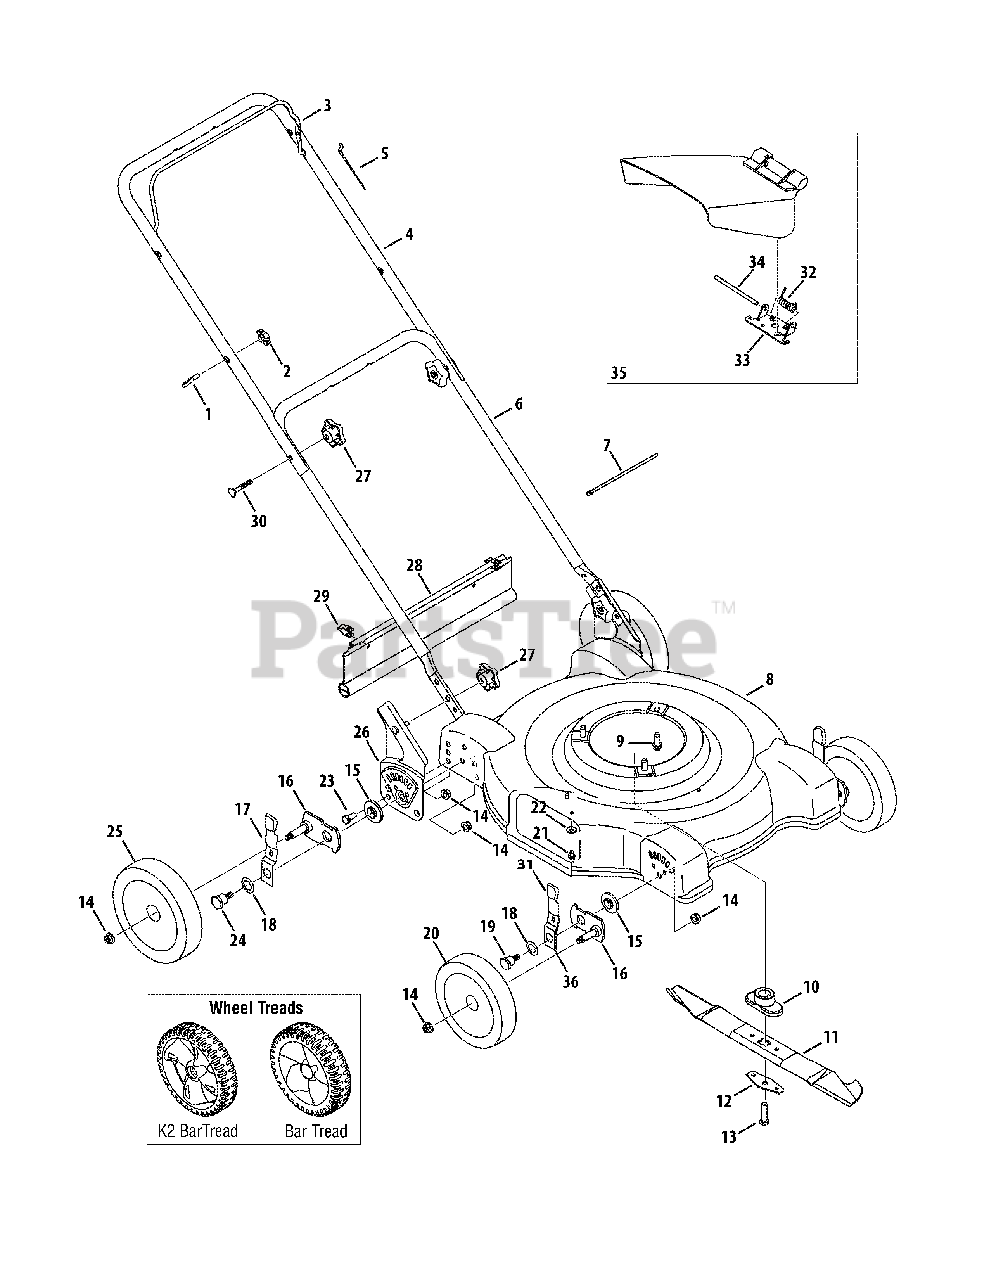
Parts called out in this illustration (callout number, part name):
1	Eye Bolt
2	Wing Nut
3	Blade Control
4	Upper Handle
5	Blade Control Cable - 37.25 inch
5	Blade Control Cable - 48.25 inch
5	Blade Control Cable - 40.00 inch
7	Cable Tie
8	Deck Assembly 22-inch
9	TT Screw, 3/8-16 x 1.0
10	Blade Adapter, #6 x 1.19, w/Star
10	Blade Adapter, 25mm x 1.19
11	Standard Blade 22-inch
12	Blade Bell Support
13	Screw, 3/8-24 x 1.5
14	Lock Nut, 3/8-16
15	Height Adjuster Bearing
16	Pivot Arm
17	Lever Ass’y. (Incl. Ref. # 31 & #36)
18	Bell Washer, .760 ID x 1.25 OD
19	Shoulder Screw
20	Front Wheel, 7 x 1.8, Bar
21	TT Screw, 1/4-20 x .5
22	Bell Washer, .265 ID x .75 OD
23	Screw, 3/8-16 x .75
24	Shoulder Screw
25	Bar Rear Wheel, 8 x 1.8, Bar
26	Handle Bracket Assembly RH
26	Handle Bracket Assembly LH
27	Star Knob
28	Trail shield
29	Hinge Clip
30	Carriage Bolt, 5/16-18 x 2
31	Knob
32	Torsion Spring
33	Chute Hinge
34	Hinge Pin
35	Hinged Chute Deflector Assembly
36	Spring Lever
